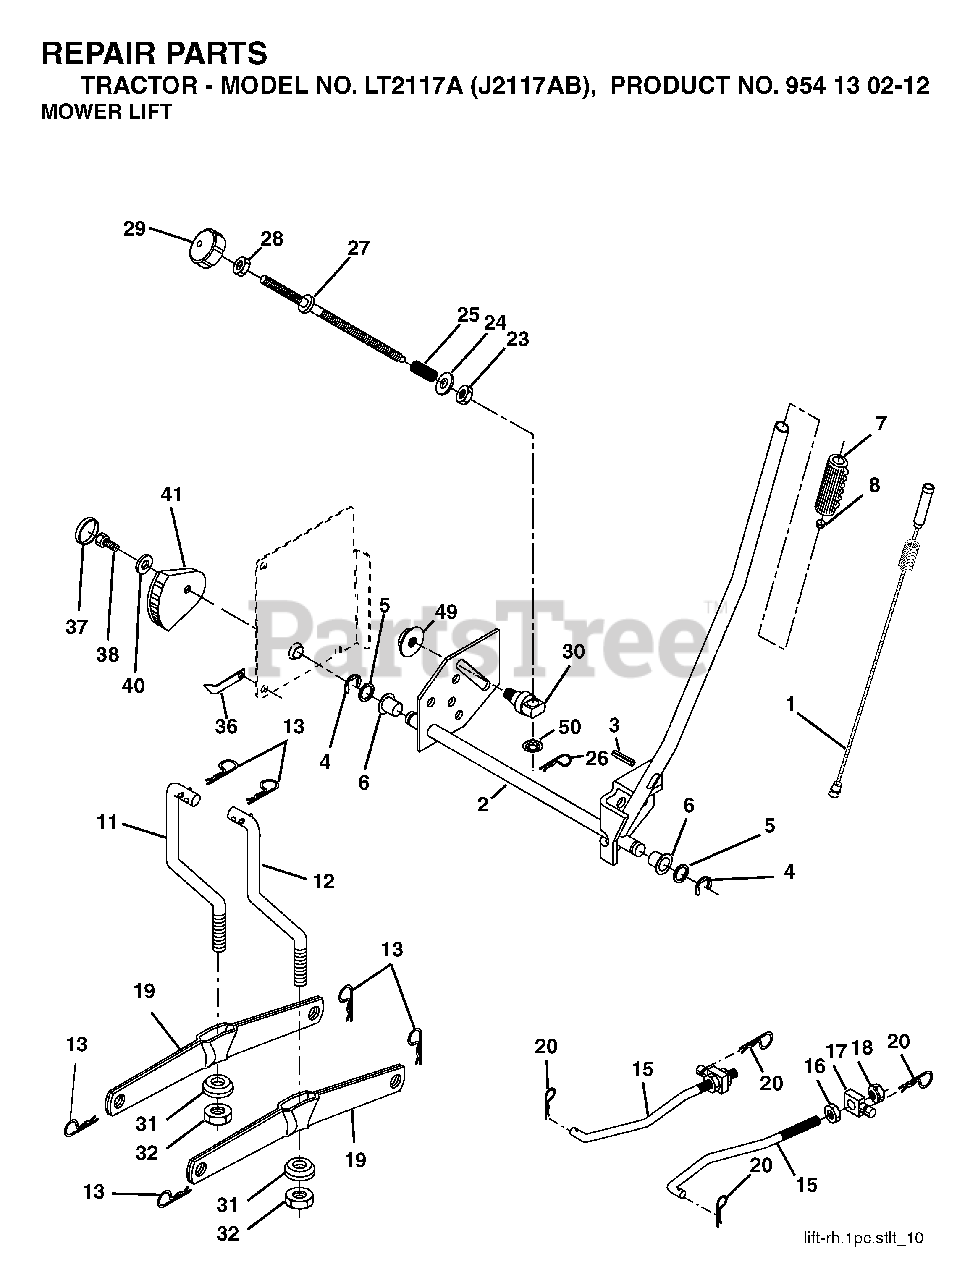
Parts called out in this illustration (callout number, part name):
1	WIRE, INNER
3	PIN GROOVE
4	RETAINING RING LT
6	BEARING.NYLON
7	GRIP HANDLE
11	LINK LIFT LH
12	LINK LIFT RH
13	RETAINER-SPRNG RB
15	LINK.SUSPENSION.FRONT
16	NUT
18	NUT
19	ARM.REAR.SUSPENSION
20	SPRING RETAINER
26	RETAINER CLIP
28	NUT
29	KNOB INF 3/8-16
31	BEARING.PIVOT.LIFT
32	NUT CROWNLOCK 3/8-24
36	POINTER, HEIGHT INDICATOR
37	PLUG,HOLE
38	SCREW 5/16-18X1
41	IND. HEIGHT STLT
49	NUT
50	NUT PUSH M
